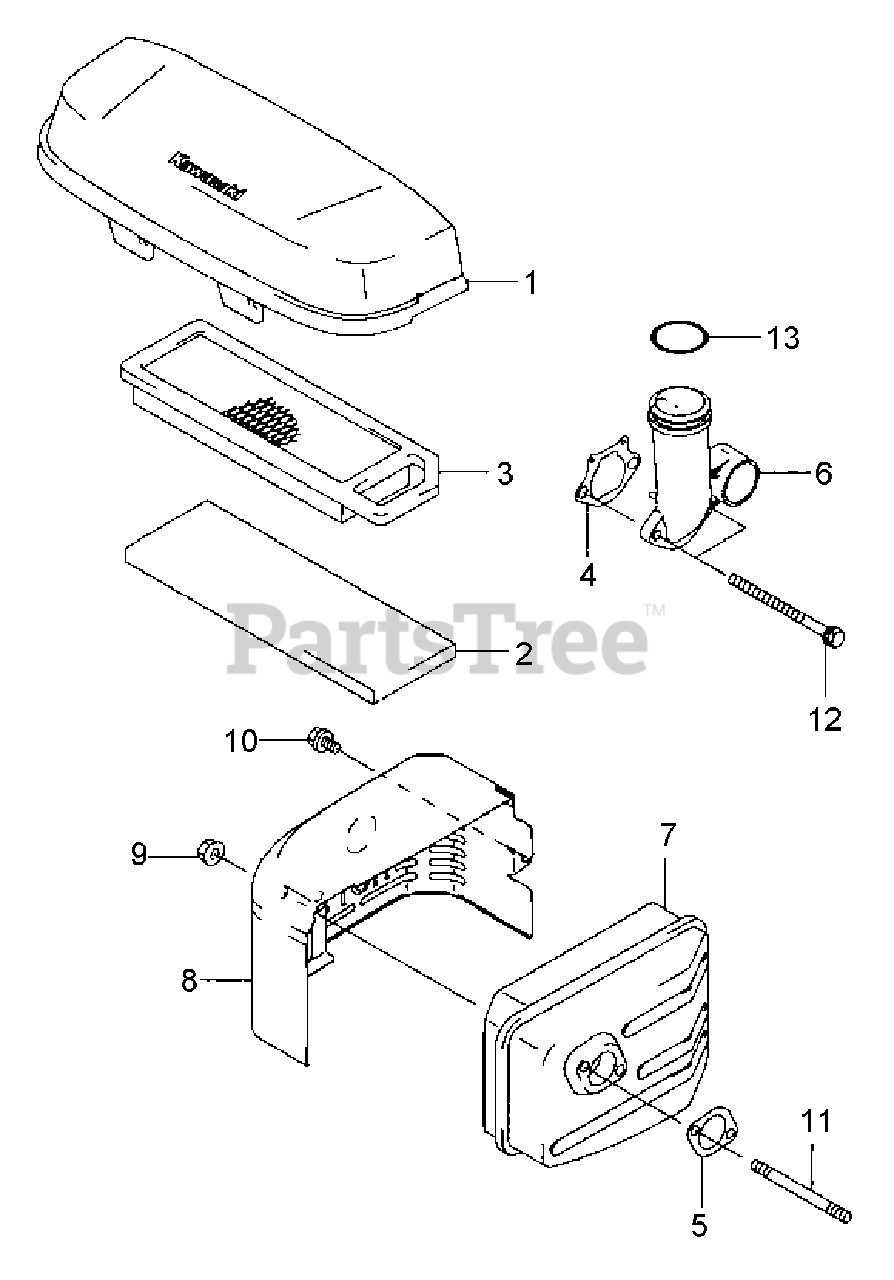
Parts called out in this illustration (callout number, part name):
1	Air Filter Case
2	Pre Filter Element
3	Air Filter Element
4	Intake Pipe Gasket
5	Muffler Gasket
7	Muffler
8	Muffler Cover
9	Nut
11	Stud Bolt
12	Bolt
